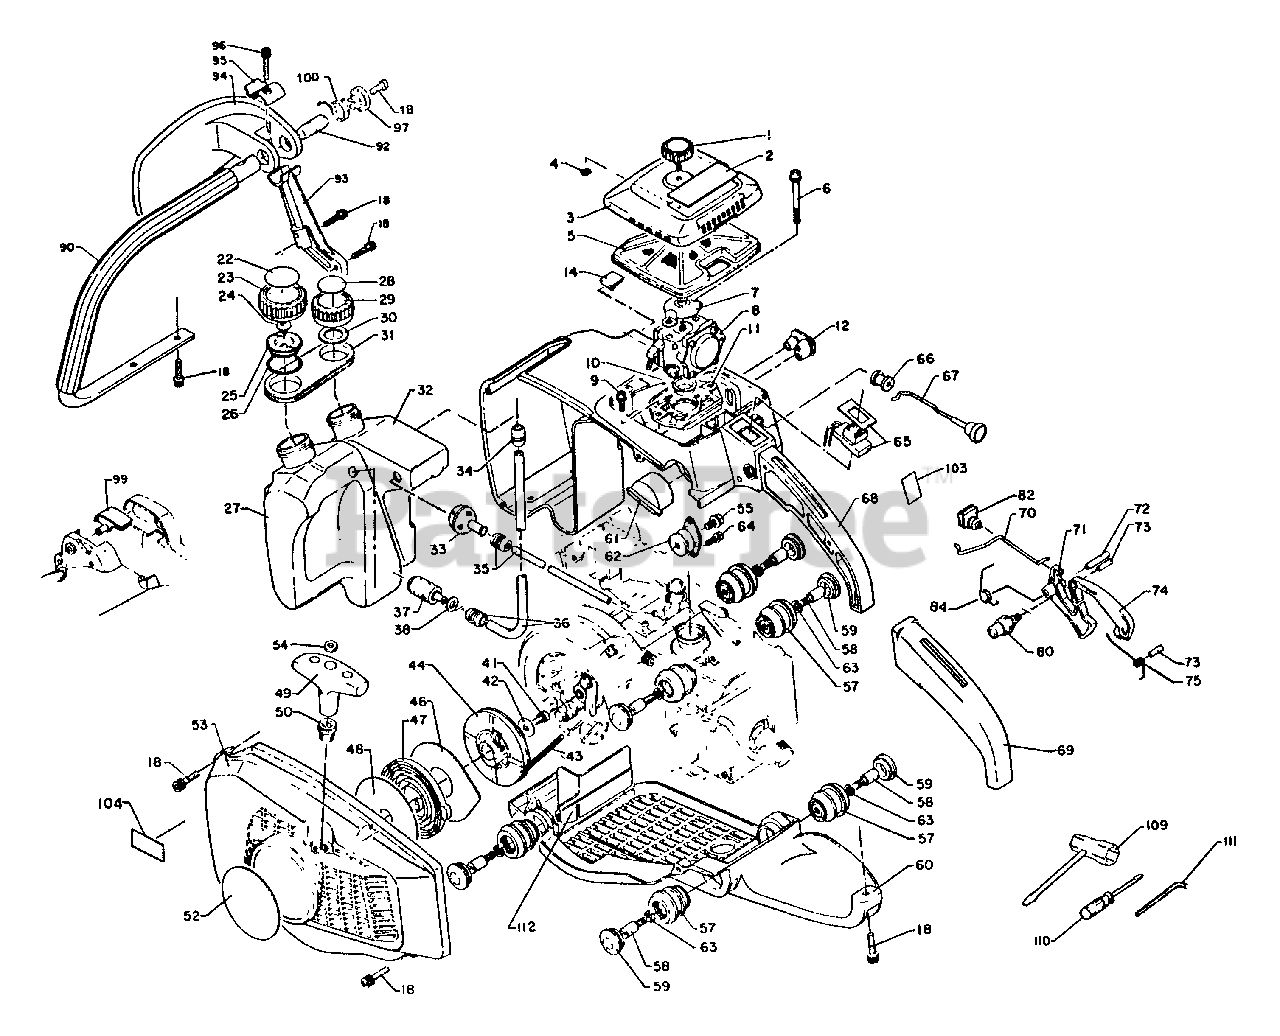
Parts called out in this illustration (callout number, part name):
1	THUMBSCREW
2	LABEL - CAUTION
3	COVER, AIR FILTER
4	O-RING 3
5	FILTER, AIR
6	SCREW 5×45
7	BRACKET, AIR FILTER
8	CARBURETOR - HDB-3A
9	SCREW 4×14
10	HOLDER
11	ADAPTER
12	GROMMET
18	BOLT 5×20
22	LABEL - FUEL MIX
23	CAP ASSY
24	VALVE, CHECK
25	HOLDER, CHECK VALVE
26	O-RING 22
27	TANK, FUEL
28	LABEL - CHAIN OIL
29	CAP ASSY
30	GASKET, CAP
31	CONNECTOR
32	TANK, OIL
33	FILTER, OIL
35	OIL PIPE KIT
36	FUEL PIPE KIT
37	FILTER, FUEL
38	WASHER 5.5×12×0.8
41	SCREW 5×10
42	WASHER 5.5×12×0.8
43	ROPE, STARTER
44	REEL, ROPE
46	PLATE, SIDE
47	SPRING, RECOIL
48	PLATE, STARTER
50	GUIDE, ROPE
52	LABEL
53	CASE, STARTER
55	SCREW 5×10
58	SCREW
59	CAP, CUSHION
60	SUPPORT
61	COVER, CUSHION
63	WASHER, SPRING 5
64	SCREW 4×10
65	SWITCH, STOP
66	GROMMET, CHOKE
67	ROD, CHOKE
68	HANDLE - REAR
69	GRIP, HANDLE
70	ROD, THROTTLE
71	TRIGGER, THROTTLE
72	PIN, SPRING 5×25
73	PIN, SPRING 4×13
74	LOCKOUT, THROTTLE
75	SPRING, LOCKOUT RETURN
80	LATCH, THROTTLE
84	SPRING, THROTTLE RETURN
90	HANDLE, FRONT
93	BRACKET, HANDLE - UPPER
94	GUARD
95	STOPPER
96	BOLT 5×30
97	RETAINER
99	COVER
103	LABEL - CHOKE
104	LABEL - NOISE
109	T-WRENCH 13×19×180
110	SCREWDRIVER, PHILLIPS
111	WRENCH, ALLEN 4 MM
112	INSULATOR
